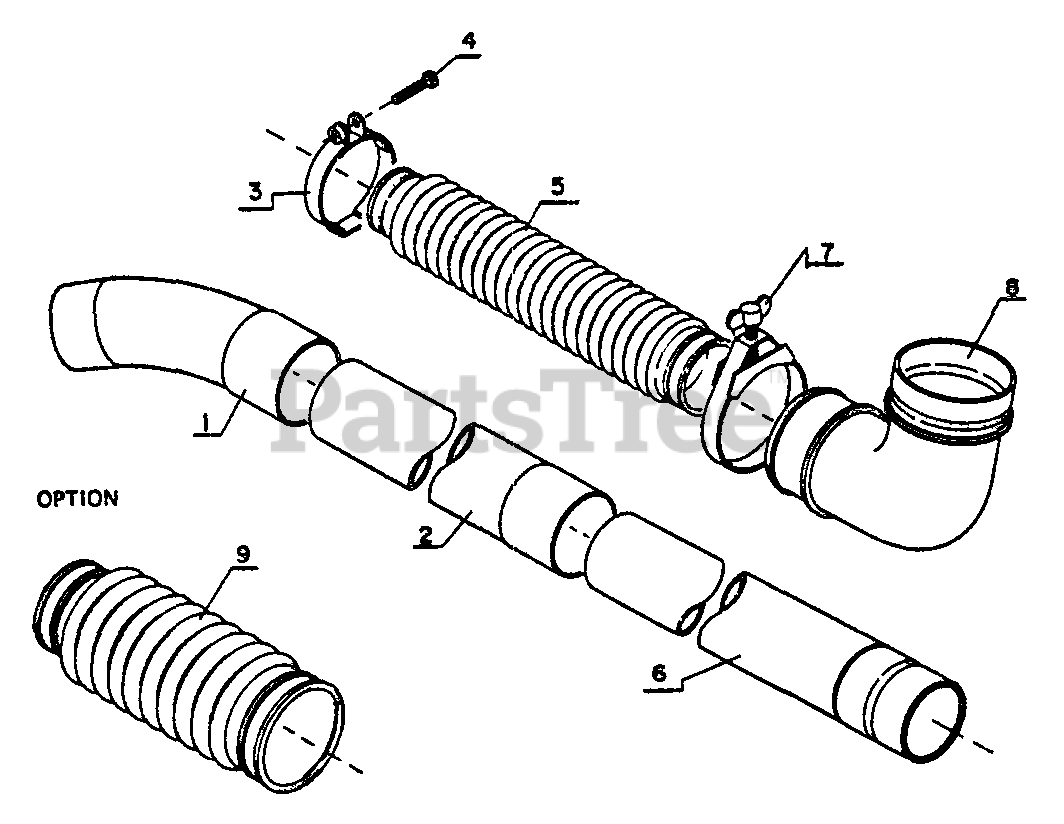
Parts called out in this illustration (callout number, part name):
1	TUBE, BLOWER - CURVED
2	TUBE, BLOWER - STRAIGHT
3	CLAMP
4	SCREW - 5X20
5	TUBE, BLOWER - FLEXIBLE
6	TUBE, BLOWER - SWIVEL
7	CLAMP
8	TUBE, BLOWER - ELBOW
9	TUBE, BLOWER - FLEXIBLE
